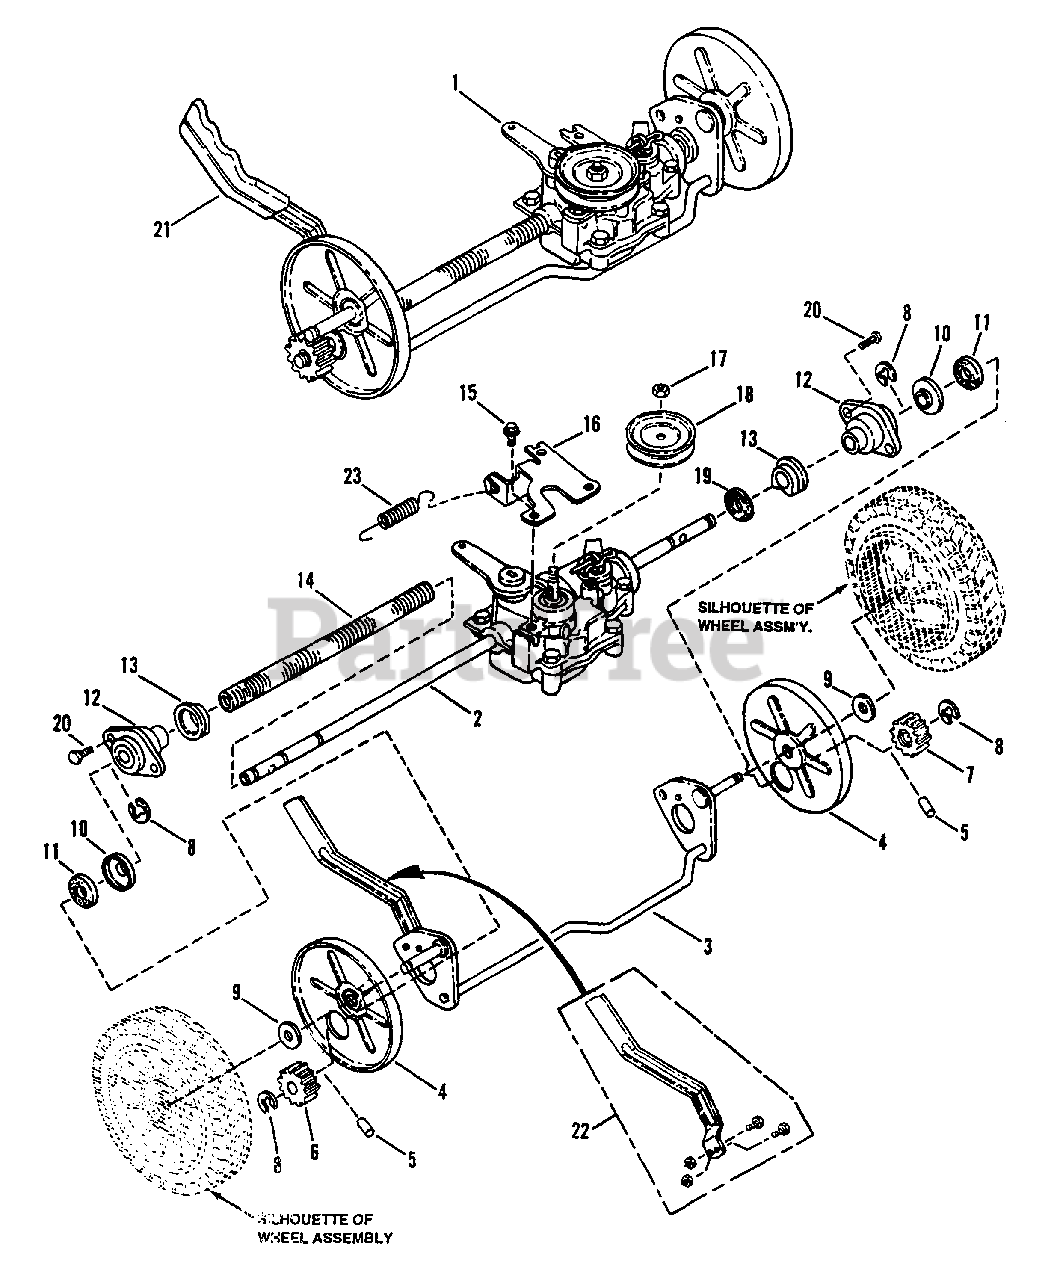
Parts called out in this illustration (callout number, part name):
1	AXLE/TRANSMISSION ASSEMBLY
2	ASSEMBLY, Transmission
3	ASSEMBLY, Rear Axle Weldment
4	SHIELD, Dust
5	PIN, Pawl, 3/16 O.D.
6	PINION, Right Hand Drive
7	PINION, Left Hand Drive
8	RING, Retaining
9	WASHER, .531 I.D. x 1.50 O.D.
10	RETAINER, Pinion Seal
11	SEAL, Pinion (Felt)
12	ASSEMBLY, Bearing Carrier
13	BUSHING, Rear Axle
14	TUBING, 5/8" I.D., Convoluted
15	SCREW, 5/16-18 x 5/8" Hex Washer Head, Self-Tapping
16	BRACKET, Transmission
17	NUT, M10-1.50 Hex Nyloc
18	PULLEY, Transmission
19	WASHER, Felt
20	SCREW, 1/4-20 x 3/8" Hex Washer Head, Self-Tapping
21	GRIP, Rear Axle
22	KIT, Height Adjusting Lever
23	SPRING, Transmission Extension
